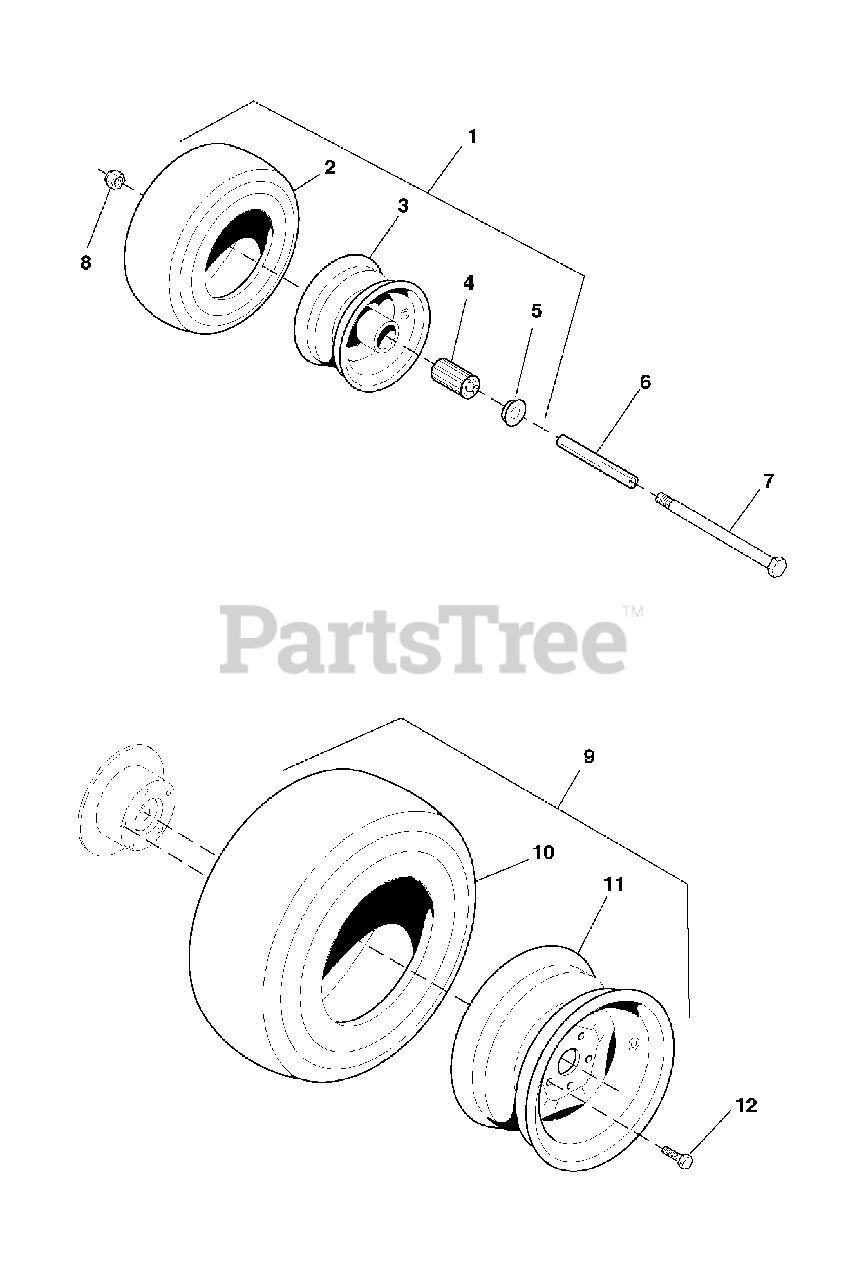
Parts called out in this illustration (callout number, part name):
1	WHEEL & TIRE ASSEMBLY, Front, 13 x 5.0 x 6, Complete (Includes Ref 2 thru 5)
2	TIRE, Front, 13 x 5.0 x 6
3	WHEEL ASSEMBLY, Front, for 13 x 5.0 x 6 Tires, Complete (Includes Ref 4 & 5)
4	BEARING, Roller (2 per tire)
5	RETAINER, Bearing (2 per tire)
6	AXLE, Front Caster
7	CAPSCREW, Hex Hd, 1-2/13 x 7-1/2
8	NUT, Hex, Nylon Lock, 1-2/13
9	WHEEL & TIRE ASSEMBLY, Rear, 23 x 10.5 x 12, Complete (Includes Ref 10 & 11)
10	TIRE, Rear, 23 x 10.5 x 12
11	WHEEL ASSEMBLY, Rear, for 23 x 10.5 x 12 Tires
12	WHEEL LUG, 1/2 x 1-5/8
